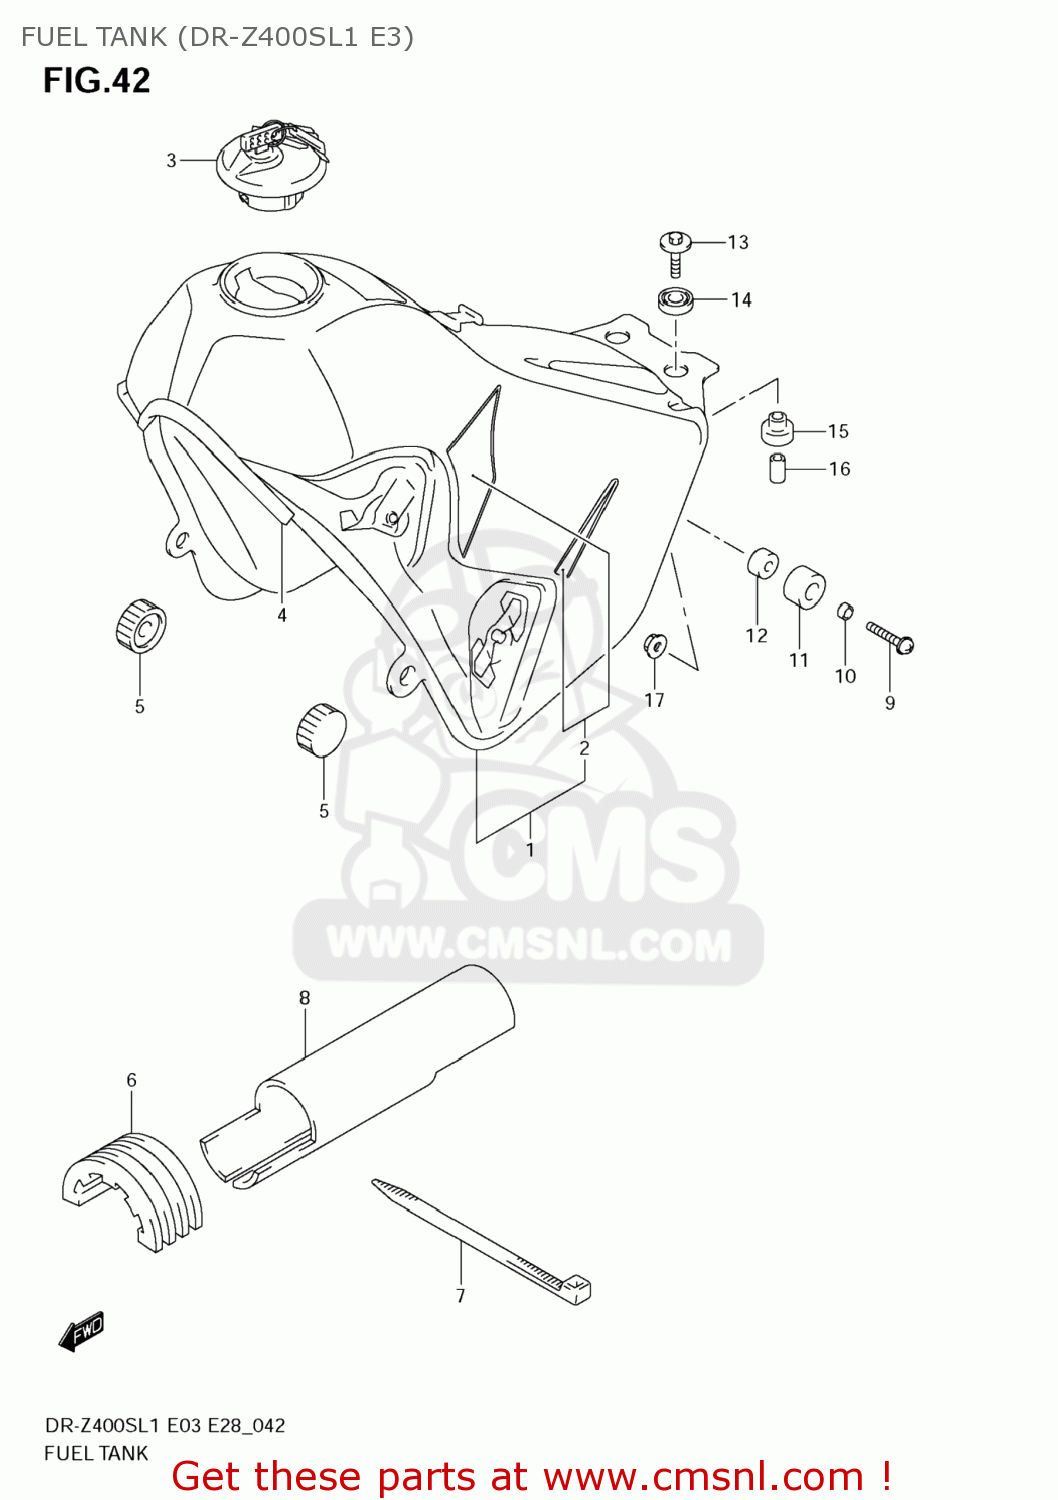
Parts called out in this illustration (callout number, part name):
1	TANK ASSY,FUEL(BLACK)
2	TAPE SET,FUEL TANK
3	CAP SET,FUEL TANK
4	MOLDING
5	CUSHION
6	CUSHION,FUEL TANK
7	CLAMP(L:300)
8	SHIELD,FUEL TANK
9	SCREW
10	SPACER(6.5X20X9)
11	CUSHION
12	SPACER(6.5X9X5)
13	BOLT(6X30)
14	CUSHION
15	CUSHION
16	SPACER(6.5X9X18)
17	NUT
